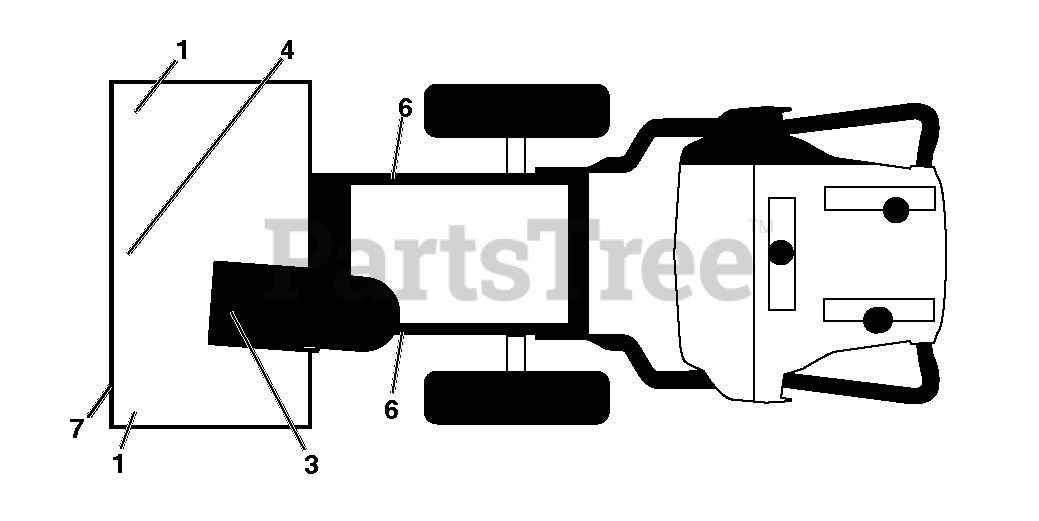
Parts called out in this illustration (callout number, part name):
1	DECAL.AUGER.SAFETY.
3	DECAL.CHUTE.SAFETY.EU/SC.17
4	DECAL.AUGER."
6	DECAL.BELT.GUARD.
7	DECAL SNOW BUCKET TRIM GRAPHIC
